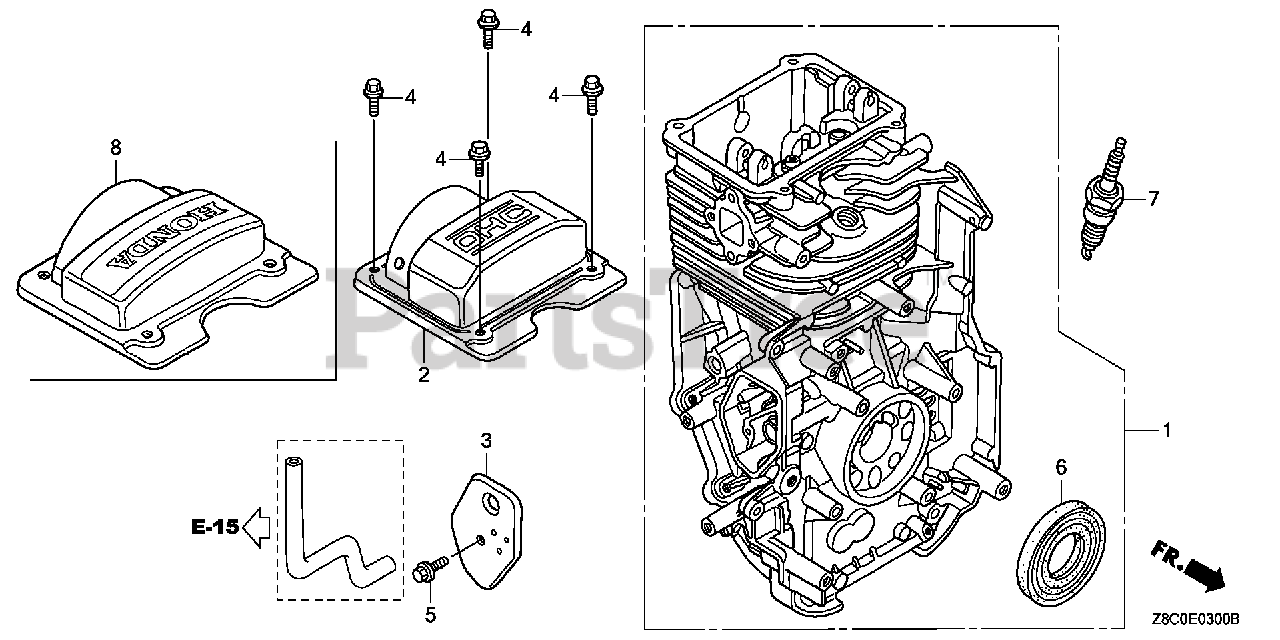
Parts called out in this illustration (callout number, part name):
1	CYLINDER ASSY.
2	COVER, CYLINDER HEAD
3	COVER, BREATHER (BREATHER VALVE ASSY.)
4	BOLT, FLANGE (6X12) (CT200)
5	BOLT, FLANGE (6X14) (CT200)
6	OIL SEAL (25.4X62X6)
7	SPARK PLUG (BPR6ES) (NGK)
